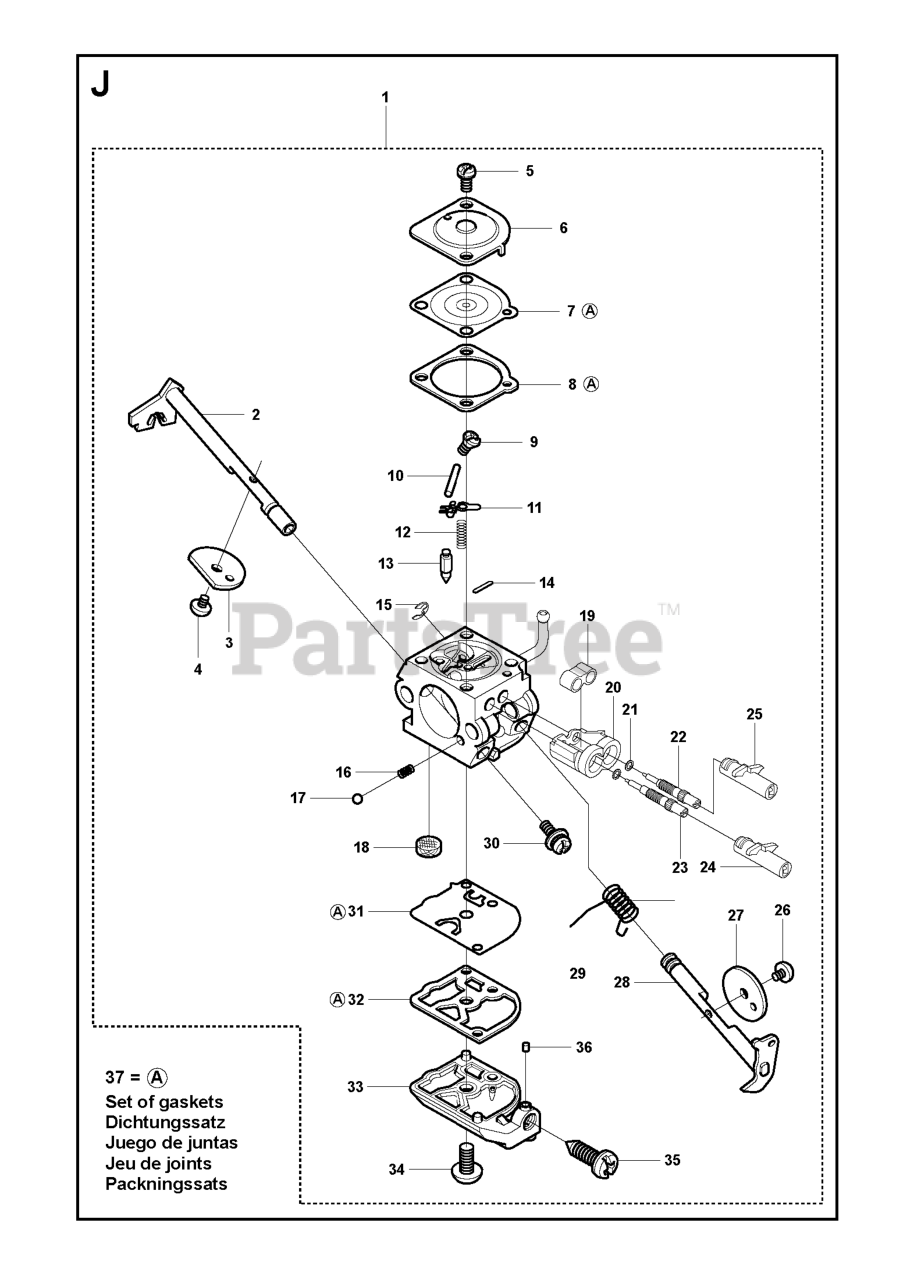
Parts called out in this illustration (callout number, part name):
1	CARBURETOR
7	METERING DIAPHRAGM
8	GASKET METERING SIDE
10	PIN RETAINING SCREW
12	SPRING
13	INLET NEEDLE
22	NEEDLE LOW SPEED
23	NEEDLE HIGH SPEED
24	LIMITER CAP
25	LIMITER CAP
27	THROTTLE FLAP
29	SPRING THROTTLE
31	PUMP DIAPHRAGM
